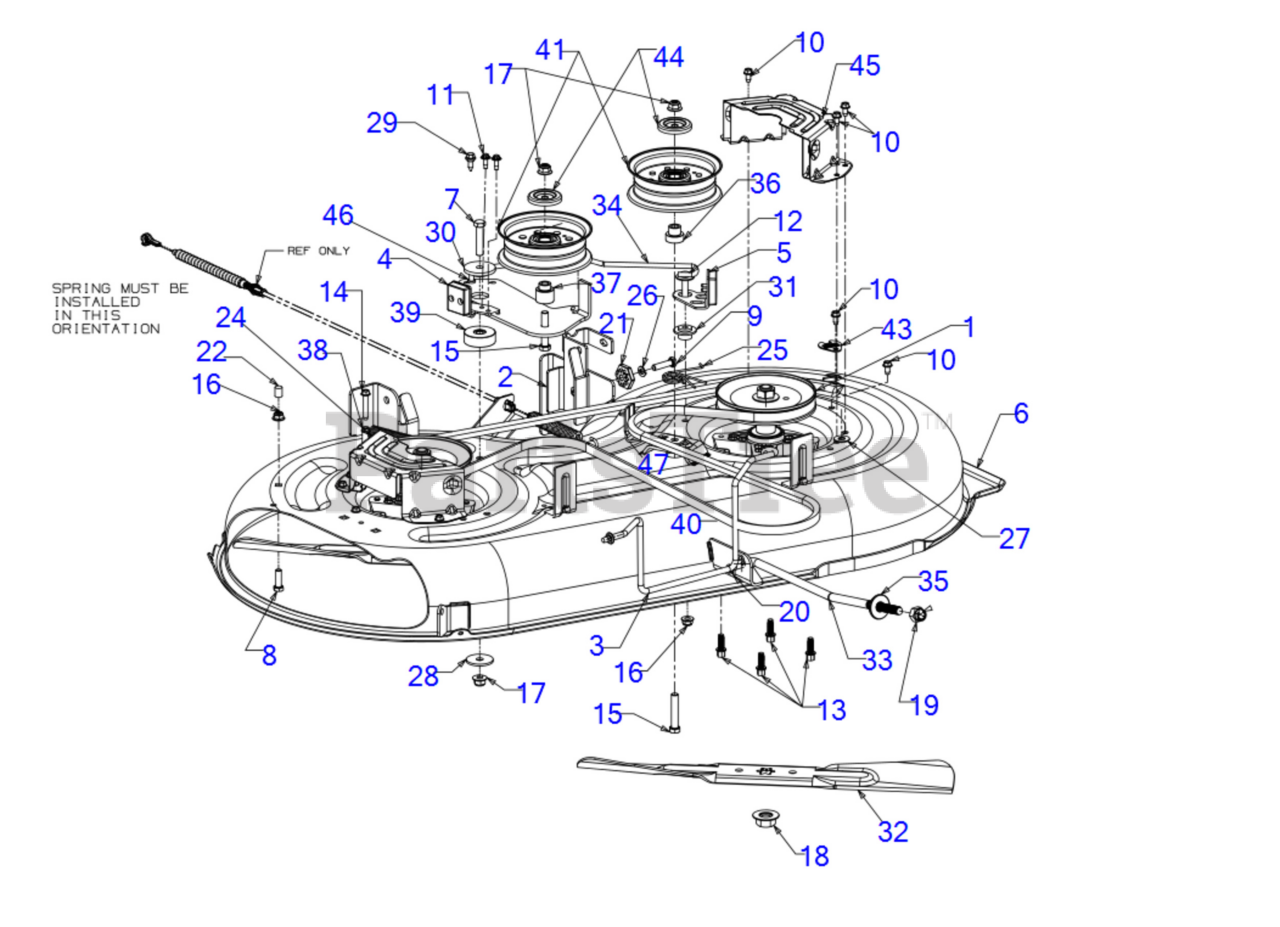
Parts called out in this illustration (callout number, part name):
1	SPINDLE ASSEMBLY
3	BELT KEEPER ROD
4	DECK BRAKE ASSEMBLY (RH)
5	DECK BRAKE ASSEMBLY (LH)
8	SCREW 5/16-18 x 1.0 GR5
9	SCREW 5/16-18 x 1.25 GR5
10	SCREW 1/4-20 X.500
11	SCREW M6-1 x .625
12	SCREW 5/16-18X1.25 GR 5
13	SCREW 5/16-18 X .875
14	SCREW 1/4-20 x 1.50"
15	SCREW 3/8-16 x 2.0 GR 8
16	FLANGE LOCK NUT 5/16-18
18	HEX NUT
20	PIN:COTTER
21	DECK ADJUSTMENT
22	VINYL CAP
24	EXTENSION SPRING
25	TORSION SPRING
26	LOCK WASHER 5/16
27	FLAT WASHER
28	FLAT WASHER .406X1.500X.105
29	SHOULDER SCREW
30	SHOULDER SPACER
31	SHOULDER SPACER .750 x .145
32	21.23" BLADE (2N1)
33	DECK FRONT LIFT ROD
34	DECK BRAKE ROD
35	DECK LIFT PIVOT CUP
36	SHOULDER SPACER
37	SHOULDER SPACER
38	SPACER
39	SPACER .385ID x 1.75OD x .585THK
40	V-BELT A x 96.5
41	IDLER PULLEY 4.50" DIA
43	DECK WASH PLUG
44	IDLER PULLEY CAP
46	DECK IDLER BRACKET
